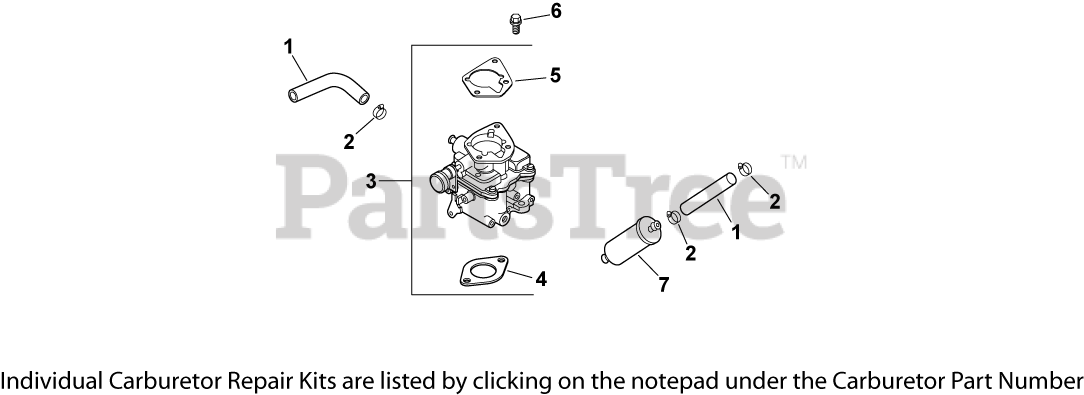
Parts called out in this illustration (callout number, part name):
1	HOSE,LW PERM.FUEL 24.00"-USE 25 111 81-S
2	CLAMP, HOSE (KM)-USE 25 237 31-S
3	KIT, CARBURETOR W/GASKETS USE 24 853 257-S
4	GASKET, CARBURETOR
5	GASKET, AIR CLEANER BASE
6	SCREW, FLG M6X1.0X25
7	FILTER, FUEL (9-12 MICRON)-USE 24 050 13
